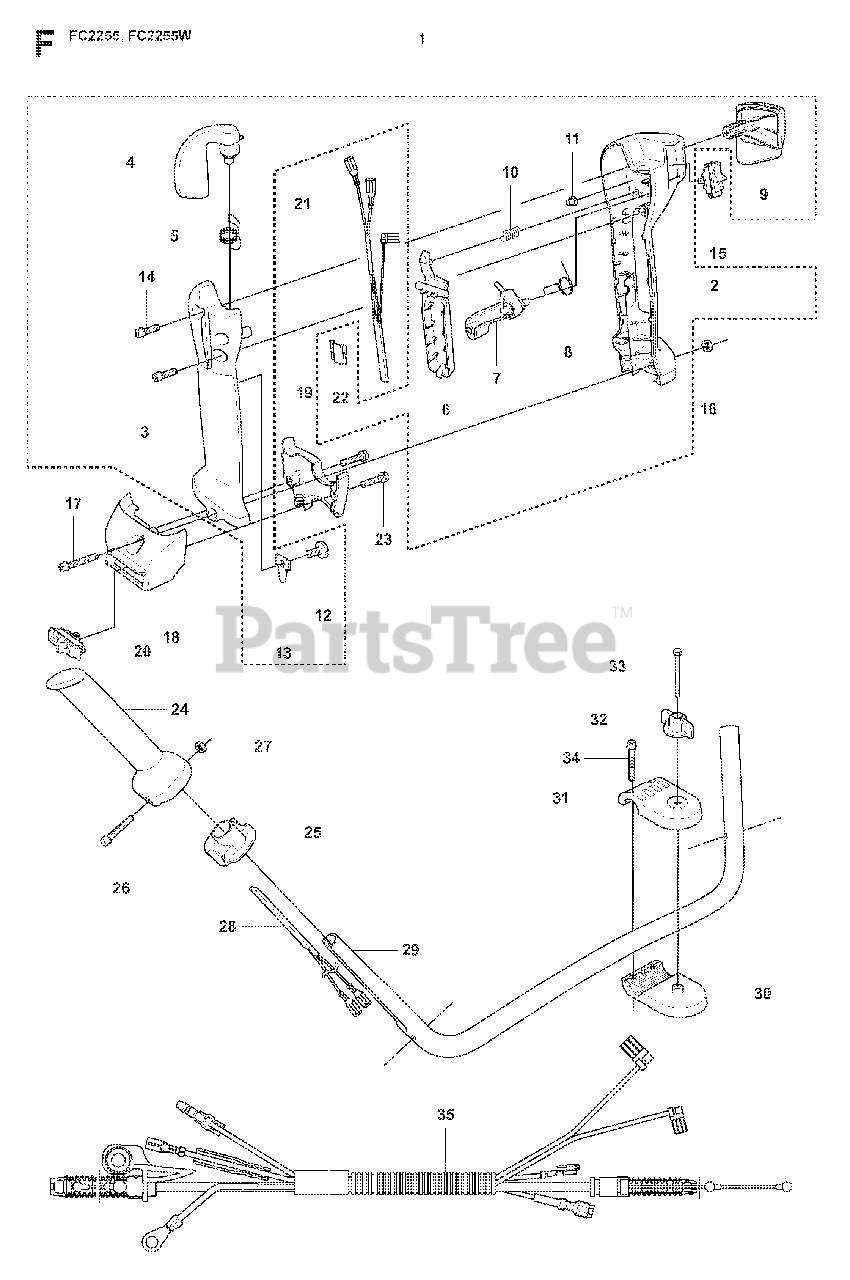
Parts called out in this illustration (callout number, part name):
2	HANDLE HALF RIGHT
5	RP SPRING
15	STOP BUTTON
16	NUT M6M M5
17	SCREW
20	SWITCH (G)
21	HEATING ELEMENT
23	SCREW
25	HANDLE FASTENER
27	NUT M6M M5
28	HEATING ELEMENT
29	%HANDLE
30	HANDLE BRACKET
31	HANDLE BRACKET
33	%SCREW
35	WIRING
